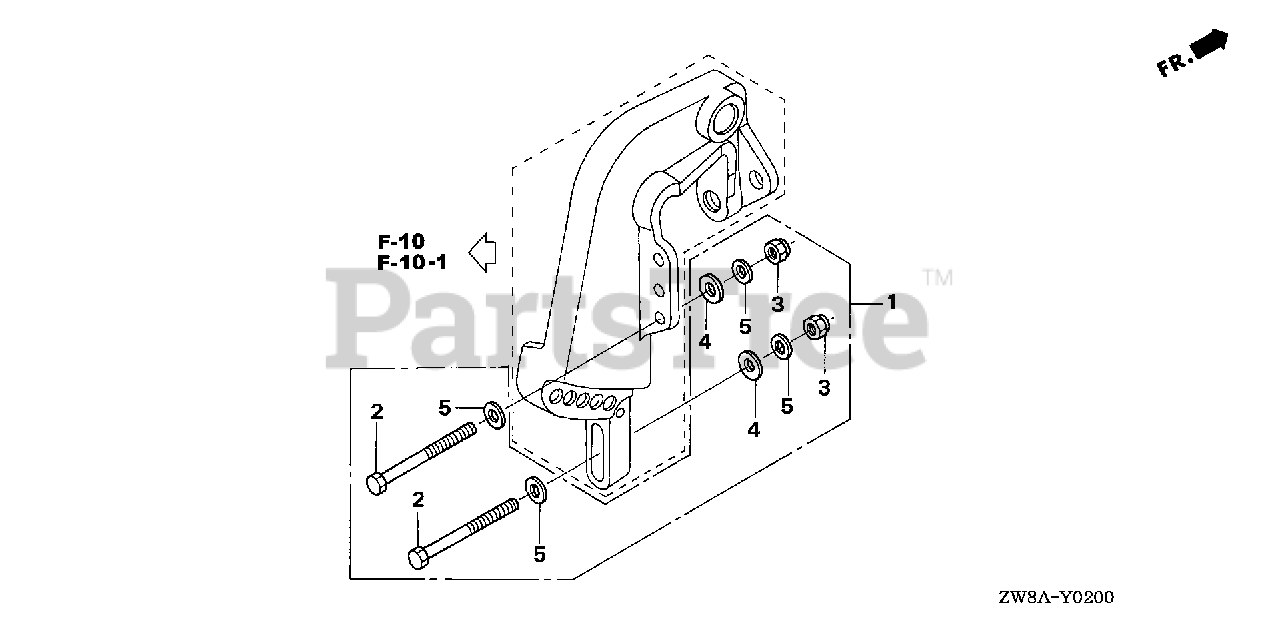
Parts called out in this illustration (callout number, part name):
1	INSTALLATION KIT, OUTBOARD
2	BOLT, HEX. (10X100)
3	NUT, SELF-LOCK (10MM)
4	WASHER, PLAIN (10MM)
5	WASHER, PLAIN (10MM)
